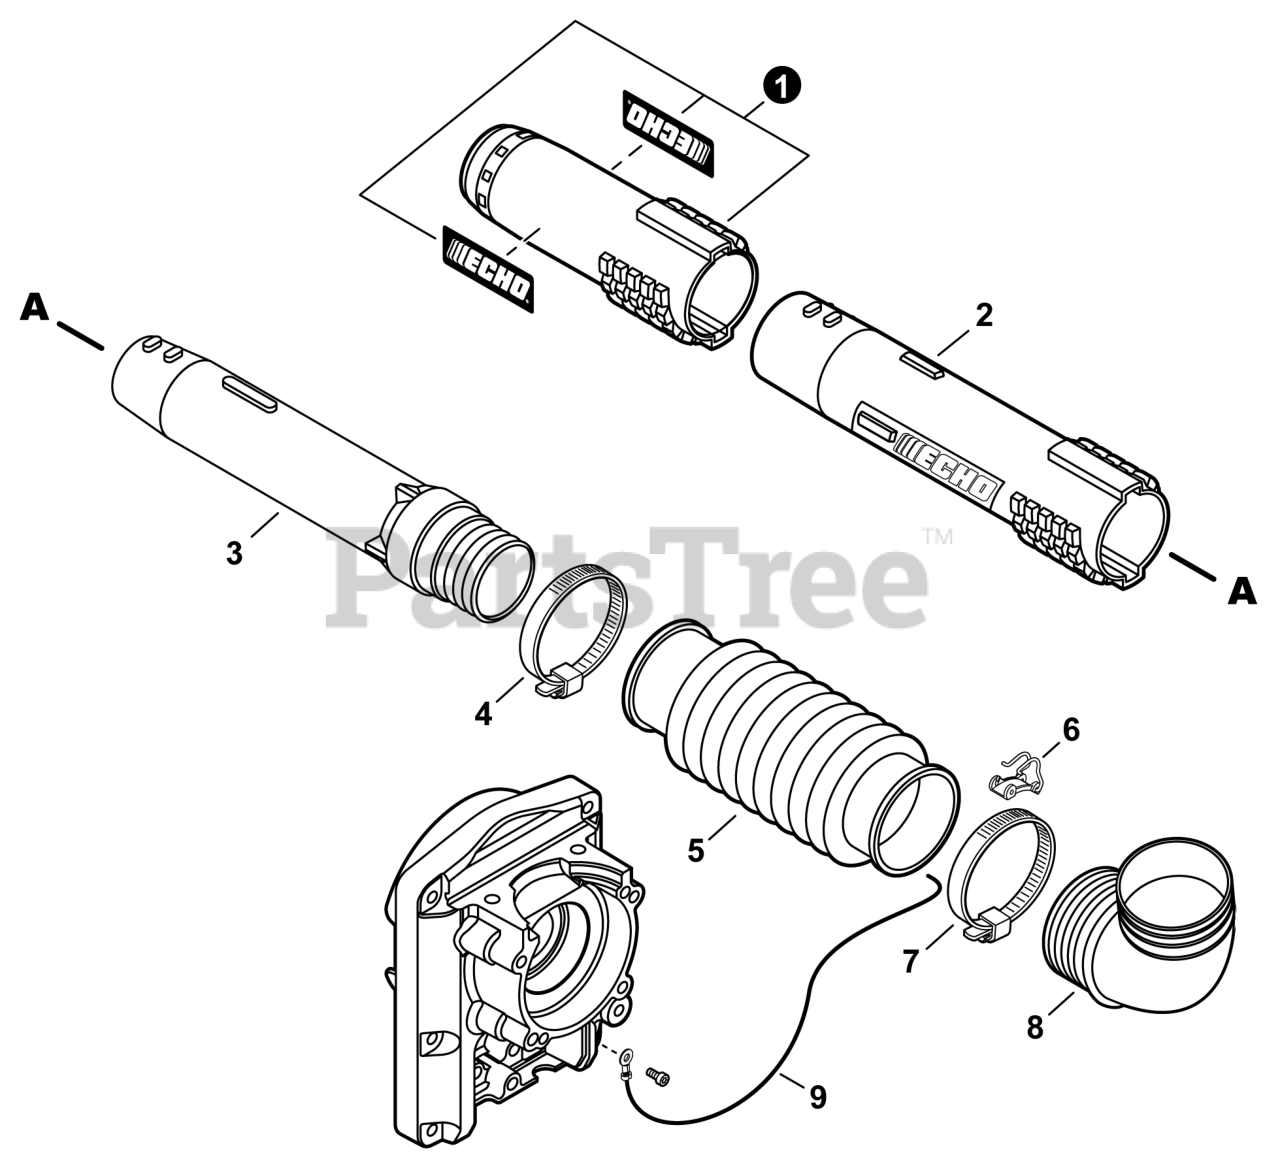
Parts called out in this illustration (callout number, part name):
1	TUBE SET, BLOWER - NOZZLE
2	TUBE, BLOWER - STRAIGHT
3	TUBE, BLOWER - SWIVEL
4	CLAMP - BAND 58.7 MM / 82.5 MM
5	TUBE, BLOWER - FLEXIBLE
6	CLIP, CABLE
7	CLAMP - BAND 77.8 MM / 101.6 MM
8	TUBE, BLOWER - ELBOW
9	WIRE, STATIC DISCHARGE
